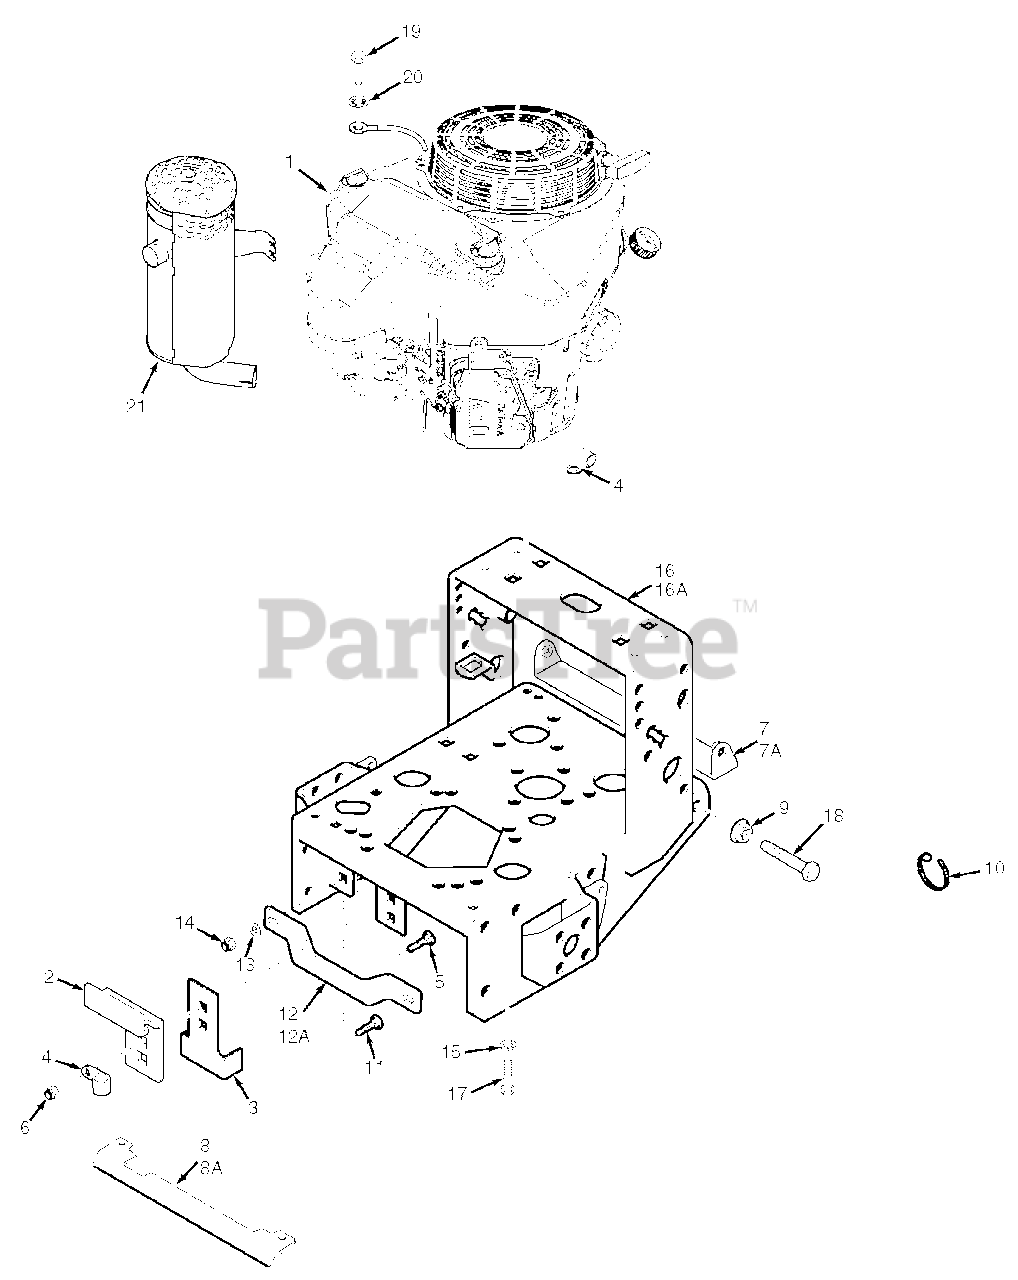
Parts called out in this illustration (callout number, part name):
1	Engine, Kawasaki 14FS (FS481V)
1	Engine, Kawasaki 15FS (FS541V)
1	Engine, Kawasaki 18FS (FS600V)
2	Plate, Clutch Bracket
3	Clutch Bracket
5	Bolt, Carriage 5/16-18 x 1"
6	Nut, 5/16-18 Elastic Stop
7	Pulley Guard, 16" Small Frame
7A	Pulley Guard, 20" Large Frame
8	Heatshield, 16" Small Frame
8A	Heatshield, 20" Large Frame
9	Nut, 5/16-18 Serr. Flange
10	Cable Tie
11	Bolt, Carriage 3/8-16 x 1-1/4"
12	Brace, 16" Small Frame
12A	Brace, 20" Large Frame
13	Flatwasher, .391 x .938 x .105
14	Nut, 3/8-16 Elastic Stop
15	Lockwasher, 3/8"
16	Engine Deck, 16" Wide w/Decals
16A	Engine Deck, 20" Wide w/Decals
17	Bolt, Hex Head 3/8-16 x 1-1/4"
18	Bolt, 5/16-18 x 2" Hex Head
19	Bolt, Hex Head M8-1.25 x 16
20	Lockwasher, 5/16" Ext. Tooth
21	Muffler, Kawasaki FS/FX
